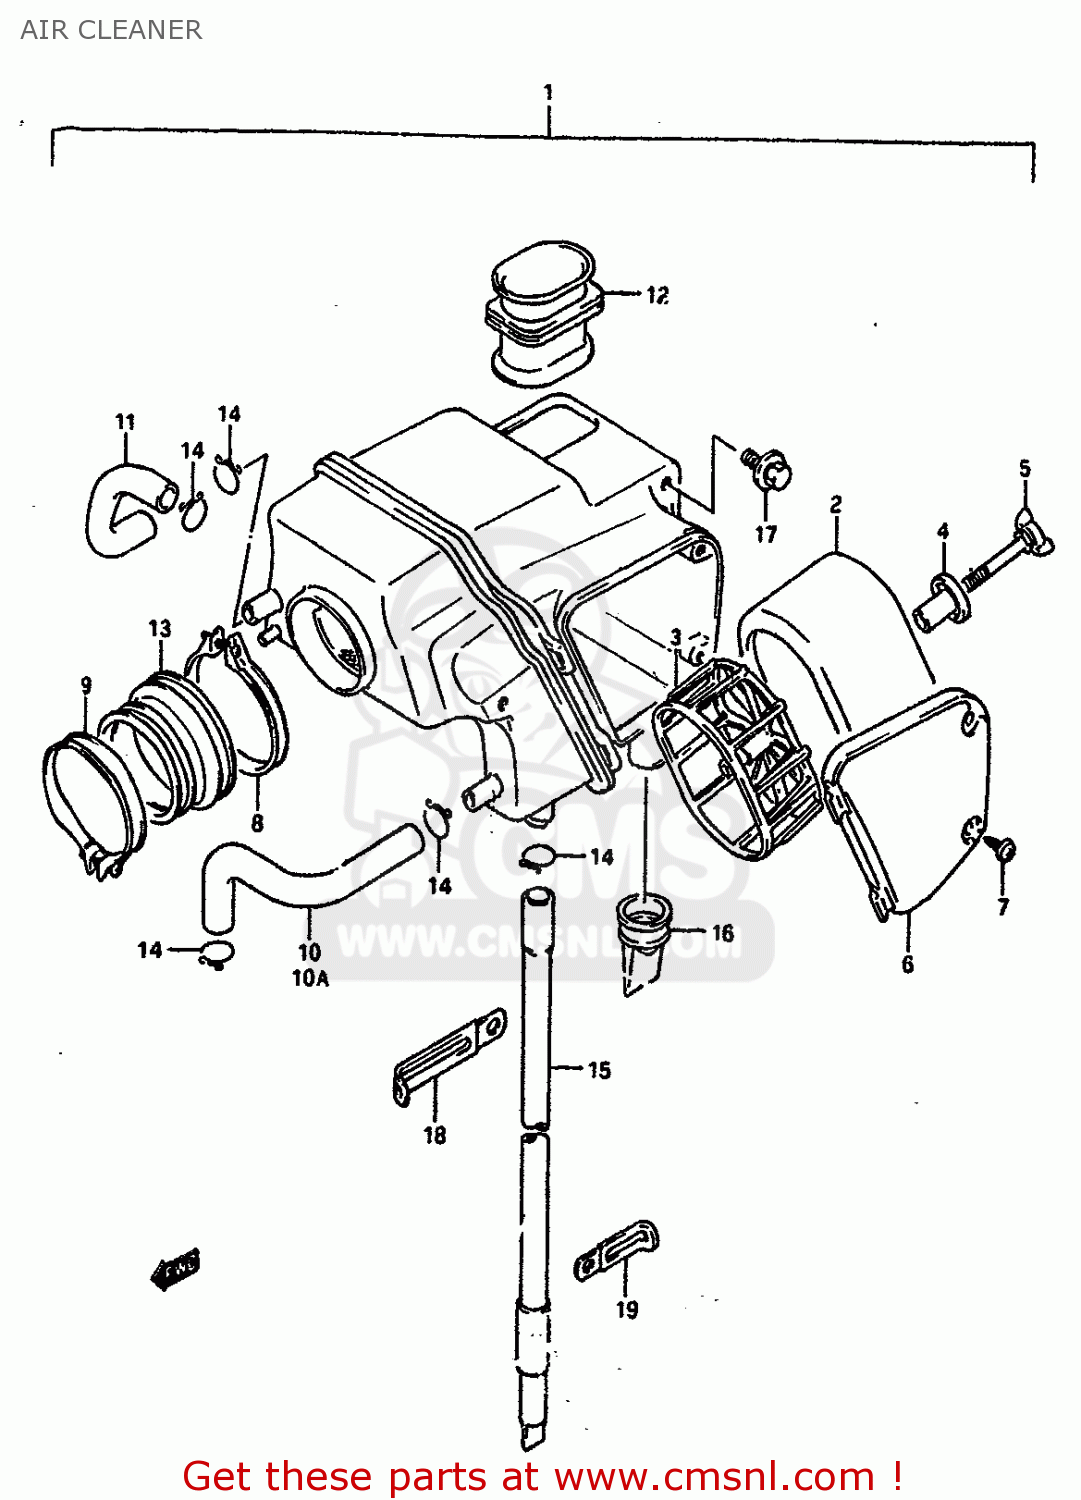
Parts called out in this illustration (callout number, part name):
1	CLEANER ASSEMBLY,AIR
2	FILTER
3	HOLDER,FILTER
4	SPACER
5	BOLT,WING
6	CAP,AIR CLEANER
7	SCREW
8	CLAMP
9	CLAMP
10	TUBE,BREATHER
10A	TUBE,BREATHER
11	TUBE,CONNECTING
12	TUBE,INLET
13	TUBE,OUTLET
14	CLIP
15	DRAIN TUBE
16	CAP,DRAIN
17	BOLT(6X14)
18	CLAMP
19	CLAMP L:35
